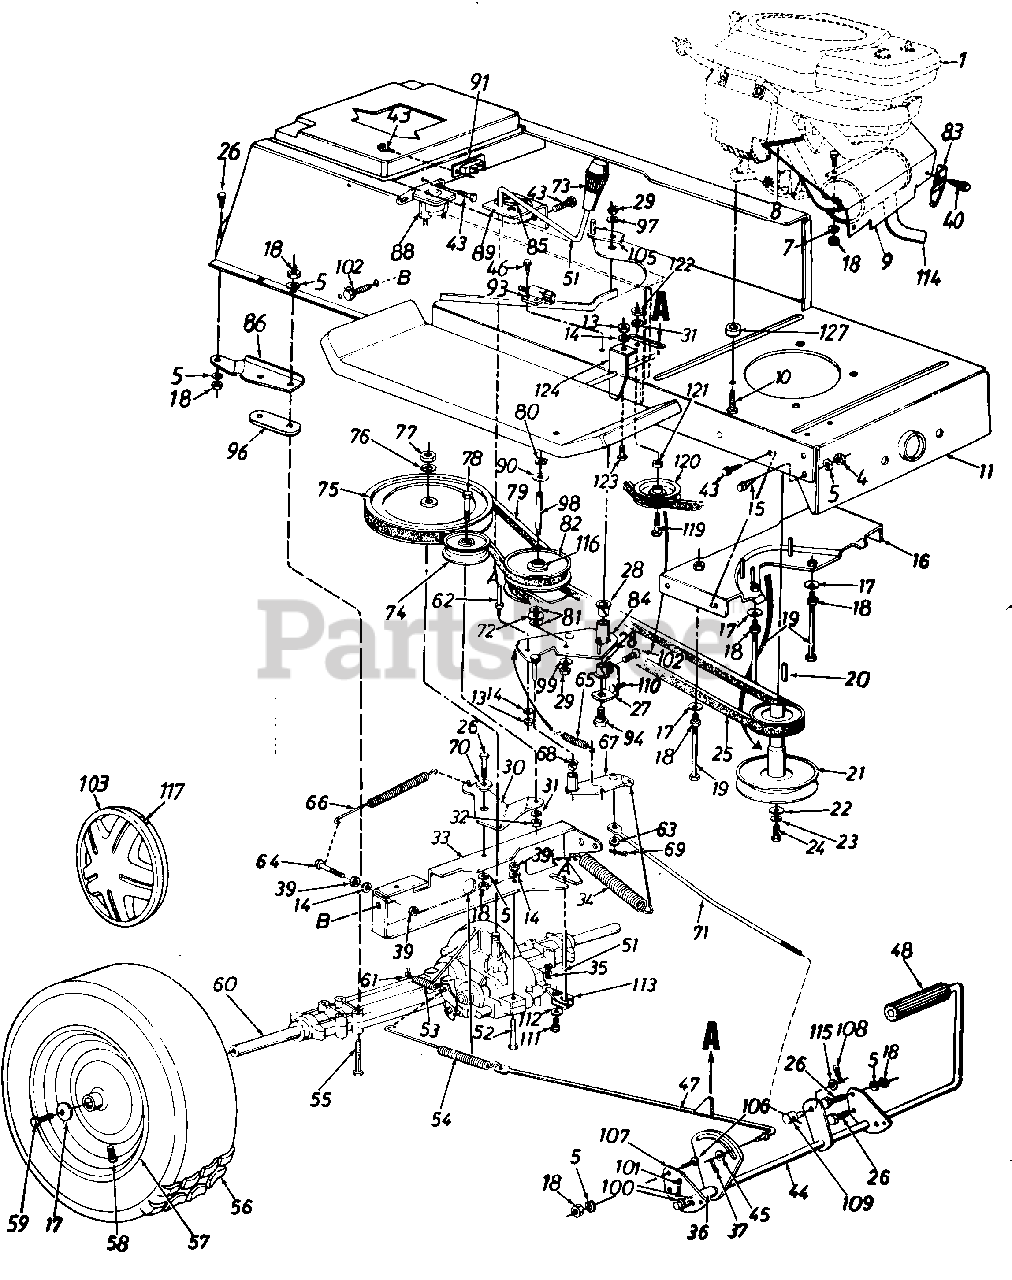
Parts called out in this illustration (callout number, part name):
1	Engine
4	Hex Nut 5/16-24 Thd.*
5	L-Wash. 5/16" I.D.*
7	Spec. L-Wash. .38" I.D. x .88"
8	Trim Strip
9	Front Heat Shield
10	Hex L-Wash. Tap Scr. 3/8-16 x 1.5" Lg.
11	Lower Frame Ass'y.
13	Hex Nut 1/4-20 Thd.*
14	L-Wash. 1/4" I.D.*
15	Rib Neck Bolt 5/16-24 x .84" Lg.
16	Belt Guard Brkt. Ass'y.
17	Bell-Wash. .345" I.D. x .88"
18	Hex Nut 5/16-18 Thd.*
19	Hex Bolt 5/16-18 x 4.0"*
20	Sq. Key 1/4" x 1/4" x 2.00"
21	Engine Pulley
22	Fl-Wash. 7/16" I.D. x 1.25"
23	L-Wash. 7/16" I.D.*
24	Hex Bolt 7/16-20 x 1.50" Lg.
25	Variable-Speed Belt
26	Hex Bolt 5/16-18 x .75" Lg.
27	Bearing Shaft Bracket Ass'y.
28	Flanged Nyliner Brg. 5/8" I.D. x .88" Lg.
29	Hex Nut 3/8-24 Thd.*
31	L-Wash. 3/8" I.D.*
32	Hex Nut 3/8-24 Thd.*
33	Transaxle Support Brkt.
34	Ext. Spring .94" O.D. x 7.58"
35	Inter. Cotter Pin
36	Spacer.63" I.D.
37	Cotter Pin 3/32" Dia. x .75"*
39	Hex Nut 1/4-28 Thd.
40	Hex AB-Tap Scr. 1/4" x .62" Lg.
43	Hex Wash. Hd. S-Tap Scr. 1/4-20 x .50" Lg.
44	Clutch/Brake Pedal Ass'y.
45	Fl-Wash.
46	Truss Mach. Scr. B-Tap Scr. #10 x .5" Lg.
47	Brake Rod Ass'y.
48	Foot Pad
51	Shift Lever Ass'y.
52	Hex Bolt 1/4-28 x 1.75" Lg.*
53	Ext. Spring .38" O.D. x 2.5"
54	Ext. Spring .59" O.D. x 7.08"
55	Hex Bolt 5/16 x 18 x 3.25" Lg.
57	Wheel Rim Only
58	Air Valve
59	Hex Bolt 5/16-24 x .75" Lg.
60	Transaxle Complete
61	Brake Return Spring Anchor
62	Belt Guard Pin 1/4-20 Thd.
63	Fl-Wash. .34" I.D. x .68" O.D.
64	Hex Bolt 1/4-28 x 1.25" Lg.
65	Ext. Spring
66	Ext. Spring .62" O.D. x 6.12"
68	Flanged Bearing
69	Cotter Pin 3/32" Dia.
70	Shoulder Spacer .27" Lg.
71	Speed Control Link
72	Truss Bearing .56 Dia. x 1 .25"
73	Shift Knob
74	Fl-Idler Pulley 3.25" x .75"
75	1/2" "V"-Pulley
76	L-Wash. 1/2" I.D.
77	Hex Jam Nut 1/2-20 Thd.
78	Hex Bolt 3/8-24 x 1.75" Lg.
79	Variable Speed Belt
80	Snap Ring .56" Dia.
81	Fl-Wash.
82	Variable Speed Pulley Ass'y. 5" O.D.
90	Teflon Washer .565" I.D.
91	Circuit Breaker
93	Safety Switch
94	Shld. Bolt 3/8-24 x 3.12" Lg.
96	Transaxle Spacer
97	Bell-Wash. .38" I.D. x .88"
98	Shaft .56" Dia. x 3.875" Lg.
99	Bell-Wash. .39" I.D. x 1.12"
100	Fl-Wash. .64" I.D. x .94"
101	Cotter Pin 3/32" Dia. x 1.0"
102	Hex Wash. Hd. Scr. 5/16-18 x.62" Lg.
103	Hub Cap
105	Belt Guard
106	Truss Mach. Scr. 5/16-18 x .75" Lg.
107	Pedal Bracket
108	Cotter Pin 3/32" Dia. x .75"
109	Ferrule
110	Hex Bolt 5/16-18 x 1.0" Lg.- (Grade 5)
111	Hex Bolt 1/4-28 x .50" Lg.
112	Bell-Wash. .265" I.D. x .75"
113	Shift Lever Link Ass'y.
114	Muffler
115	Fl-Wash. .385" I.D. x .62"
116	Needle Brgs
117	Spring Clip
119	Hex Bolt 3/8-16 x 1.25" Lg.
120	Fl-Idler w/Flanges 2.75" O.D.
121	Fl-Wash. .39" I.D. x 1.12" O.D.
122	Hex Nut 3/8-16 Thd.
123	Hex Bolt 1/4-20 x .62" Lg.
124	Spring Hanger Brkt.
127	Spacer 5/16" I.D.
